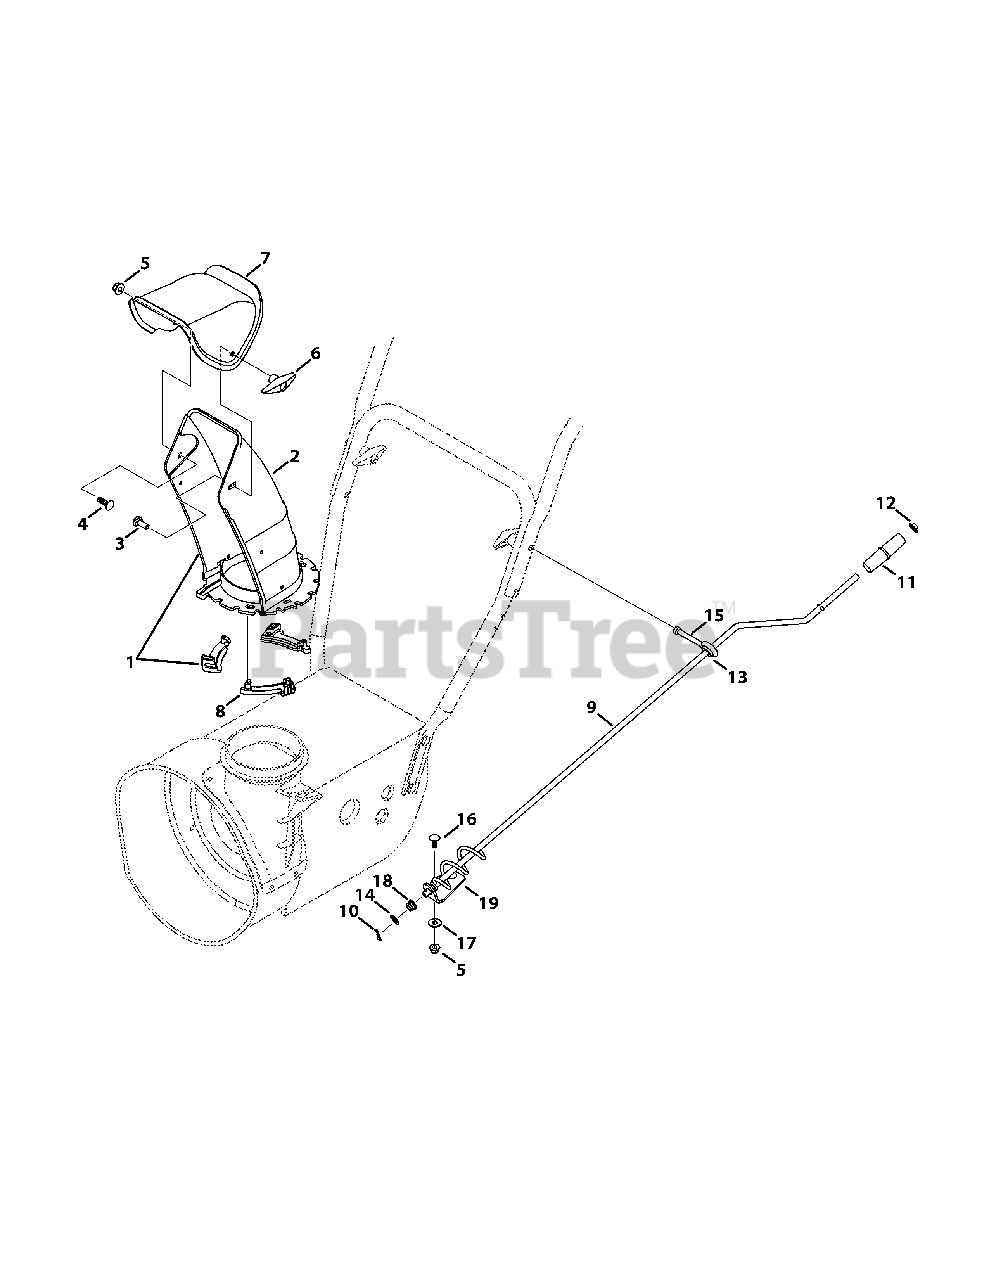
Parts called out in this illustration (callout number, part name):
1	Lower Chute Assembly
2	Lower Chute
3	Carriage Bolt, 5/16-18 x 1.00
4	Carriage Bolt, 5/16-18 x .750
5	Flange Lock Nut, 5/16-18
6	Wing Knob
7	Upper Chute
8	Flange Keeper
10	Cotter Pin, .072 x 1.13
11	Crank Knob
12	Push Cap, 3/8
13	Rubber Grommet
14	Flat Washer, .375 x .738 x .063
16	Carriage Screw, 5/16-18 x 1.00
17	Flat Washer, .349 x .879 x .063
18	Plastic Bushing, .380 ID
19	Chute Crank Bracket
